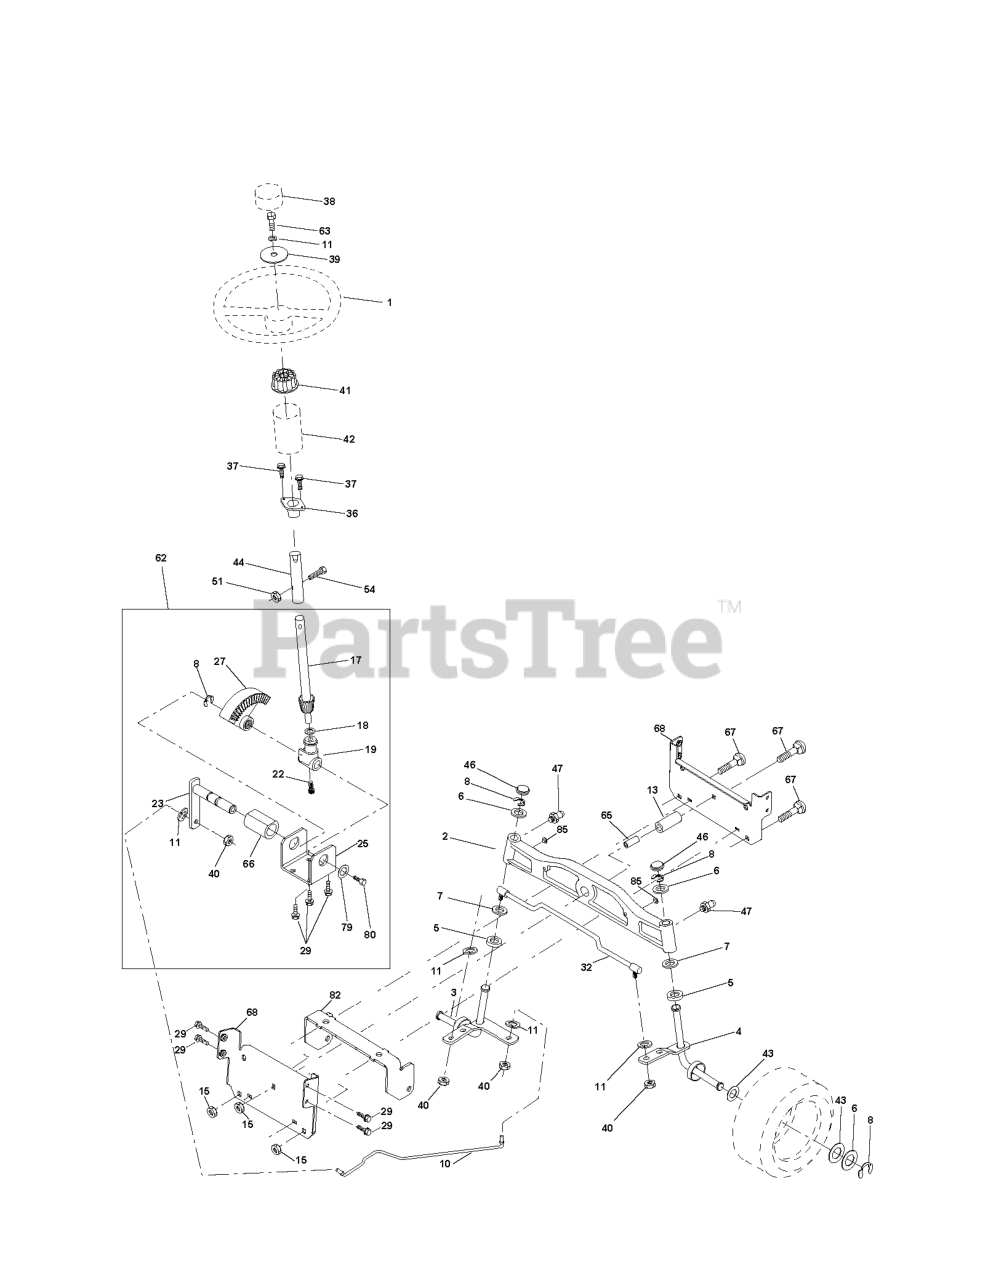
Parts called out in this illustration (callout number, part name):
1	STEERING WHEEL
2	AXLE
3	SPINDLE.ASM.LH.15"TIRES
4	SPINDLE.ASM.RH.15"TIRES
5	THRUST WASHER
10	DRAGLINK.15".TIRES
11	WASHER, LOCK 3/8
13	TUBE, PIVOT AXLE
15	NUT
17	SHAFT ASM STEERING
18	THRUST WASHER
19	STEERING SHAFT SUPPORT
22	SCREW.HX.WSH.HD
23	SHAFT ASSY PITTMAN
25	BRACKET STEERING
27	GEAR.SECTOR
29	SCREW 3/8-16X3/4
32	ROD.ASM.TIE.BALL.JOINT.NOVAN
36	BUSHING, STEERING
37	SCREW.TT.#10-32X.5.3/8.FLANGE
38	CAP.WHEEL.STEERING.GREY
39	Washer 13/32 x 1-1/20 x 11 Gauge
40	GRIPCO NUT
41	STEERING WHEEL ADAPTOR
42	BOOT STEERING
44	EXT SHAFT STEERING
46	CAP.SPINDLE.BLACK
47	ZERK M
51	NUT.71038.31-18.HEX.NYLOCK
54	BOLT.5/16-18X1-1/4 FULL.THREAD
62	STEERING KIT
65	SPACER BRACE AXLE
66	BEARING ARM
67	BOLT CARRIAGE
68	BRACE.AXLE.15"TIRES
79	WASHER
80	BOLT.HX.NYLON3/8-16X
82	BRACKET
85	FASTENER.XMAS.TREE
